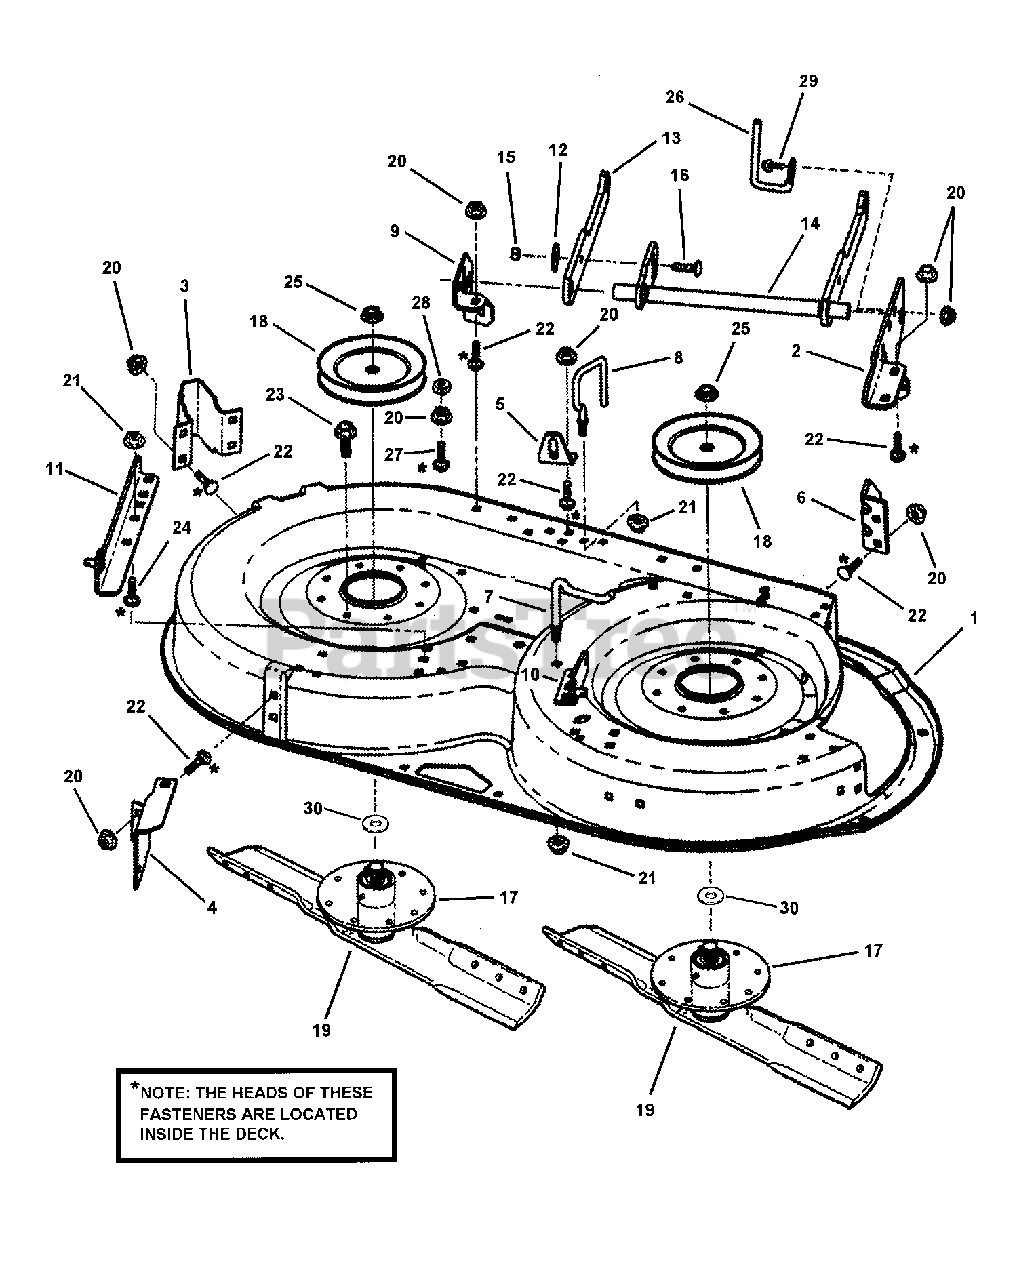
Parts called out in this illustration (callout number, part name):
1	DECK, 38" Cutting
2	BRACKET, Front Linkage
3	BRACKET, L.H. Front Gage Wheel
4	BRACKET, L.H. Rear Wheel
5	ANGLE, Front
6	BRACKET, R.H. Front Gage Wheel
7	CRADLE, Spring
8	GUIDE, Belt Dual Spindle Brake
9	BRACKET, Front Lift Arm- LS
10	BRACKET, Sector Lift R.H. Rear
11	BRACKET, Sector Lift L.H. Rear
12	WASHER, Cone, 13/32 x 1-13/32" Diameter
13	FRONT LIFT ARM, 38" Deck
14	WELDMENT, Front Lift Arm
15	NUT, 5/16-18 Hex Center Lock
16	BOLT, 5/16-18 x 1-1/8" Short Neck Carriage, GR5
17	ASSEMBLY, 38" Spindle
18	PULLEY, 5-1/2" Dia. A/B V (Spindle)
19	BLADE, 38" Cutting Deck, 19.64" Long
20	NUT, 5/16-18 Hex Flange Lock, GR5
21	NUT, 3/8-16 Hex Flange Lock
22	BOLT, 5/16-18 x 5/8" Short Neck Carriage, GR5
23	BOLT, 3/8-16 x 3/4" Hex Washer Self-Tap
24	BOLT, 3/8-16 x 3/4" Short Neck Carriage, GR5
25	NUT, 5/8-18 Hex Nyloc
26	GUIDE, Belt Side Rail
27	BOLT, 5/16-18 x 1-1/8" Short Neck Carriage, GR5
28	NUT, 5/16-18 Hex Center Lock, GR5 or B
29	SCREW, 5/16-18 x 3/4" Hex Washer Self-Tap
30	SPACER, Pulley, 1.755" OD, .655" ID, .280" Thick
